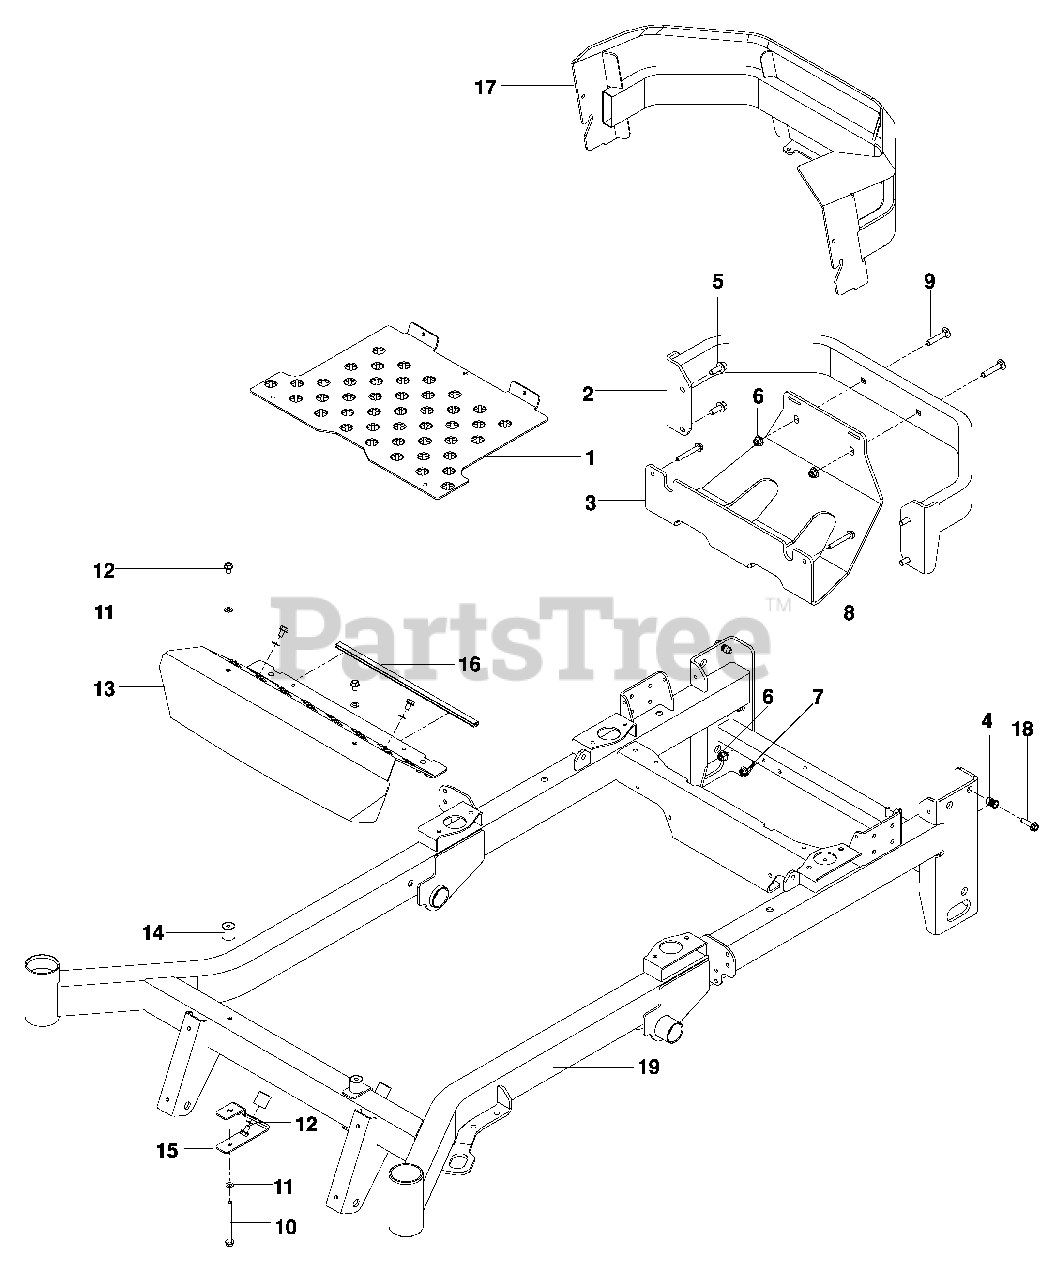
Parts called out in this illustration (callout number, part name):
2	BUMPER, REAR
3	PLATE, SKID
4	NUTSERT 5/16-18
5	SCREW 3/8-16 x 1 HEX FLG
6	NUT 3/8-16 HEX FLG NYLOC
7	NUT 5/16-18 HEX FLG NYLOC
8	SCREW 5/16-18 x 2¼ HEX FLG
9	BOLT 3/8-16 x 2 RD HD
10	SCREW 5/16-18 x 3¾ HEX FLG
11	WASHER 5/16 DISC SPRING
12	SCREW 5/16-18 x ½ SLF TAP
14	MOUNT, F/F INSERT
15	BRACKET, REST MOUNT
16	FLEX TRIM
17	GUARD, REAR
18	SCREW 5/16-18 x 1½ TPBLT
19	FRAME w/ SAFETY DECALS
20	FRAME w/ SFTY DECALS 72"
